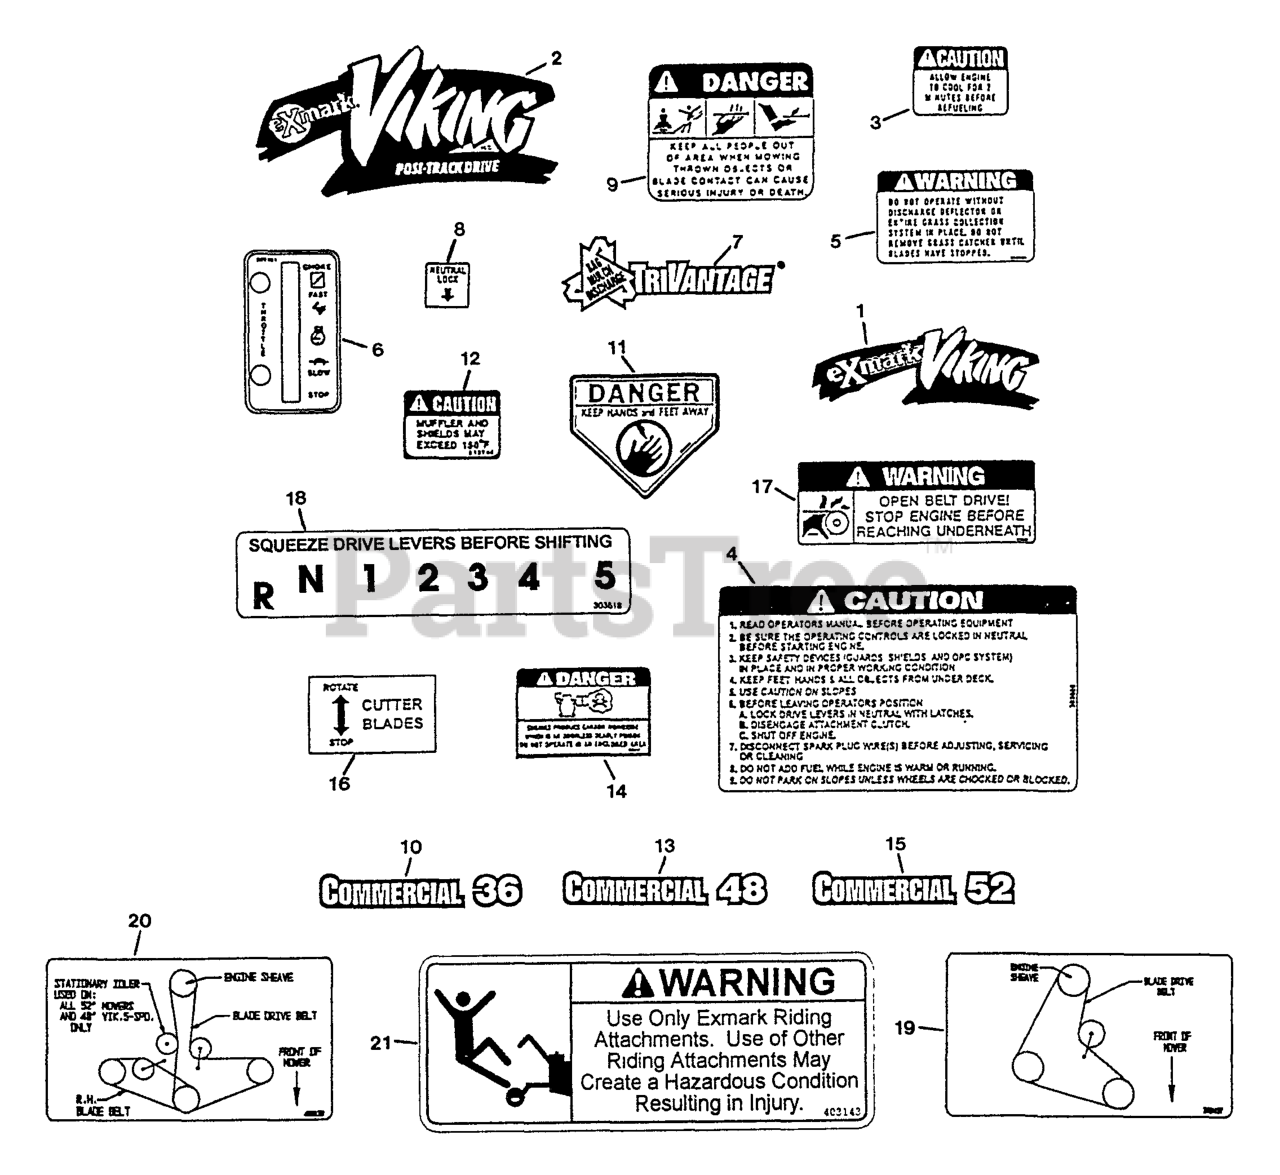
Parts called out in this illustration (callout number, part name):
4	LABEL,INSTRUCTION
5	DECAL-WARNING, DISCHARGE
8	DECAL,NEUTRAL LOCK
9	DECAL-DANGER
10	DECAL,COMMERCIAL 36
11	DECAL-DANGER
13	DECAL,COMMERCIAL 48
15	DECAL,COMMERCIAL 52
16	DECAL,CUTTER BLADE
17	DECAL,BELT DRIVE
18	DECAL,SHIFTER
19	DECAL,BELT ROUTING 32/36
21	DECAL,SULKY WARNING
